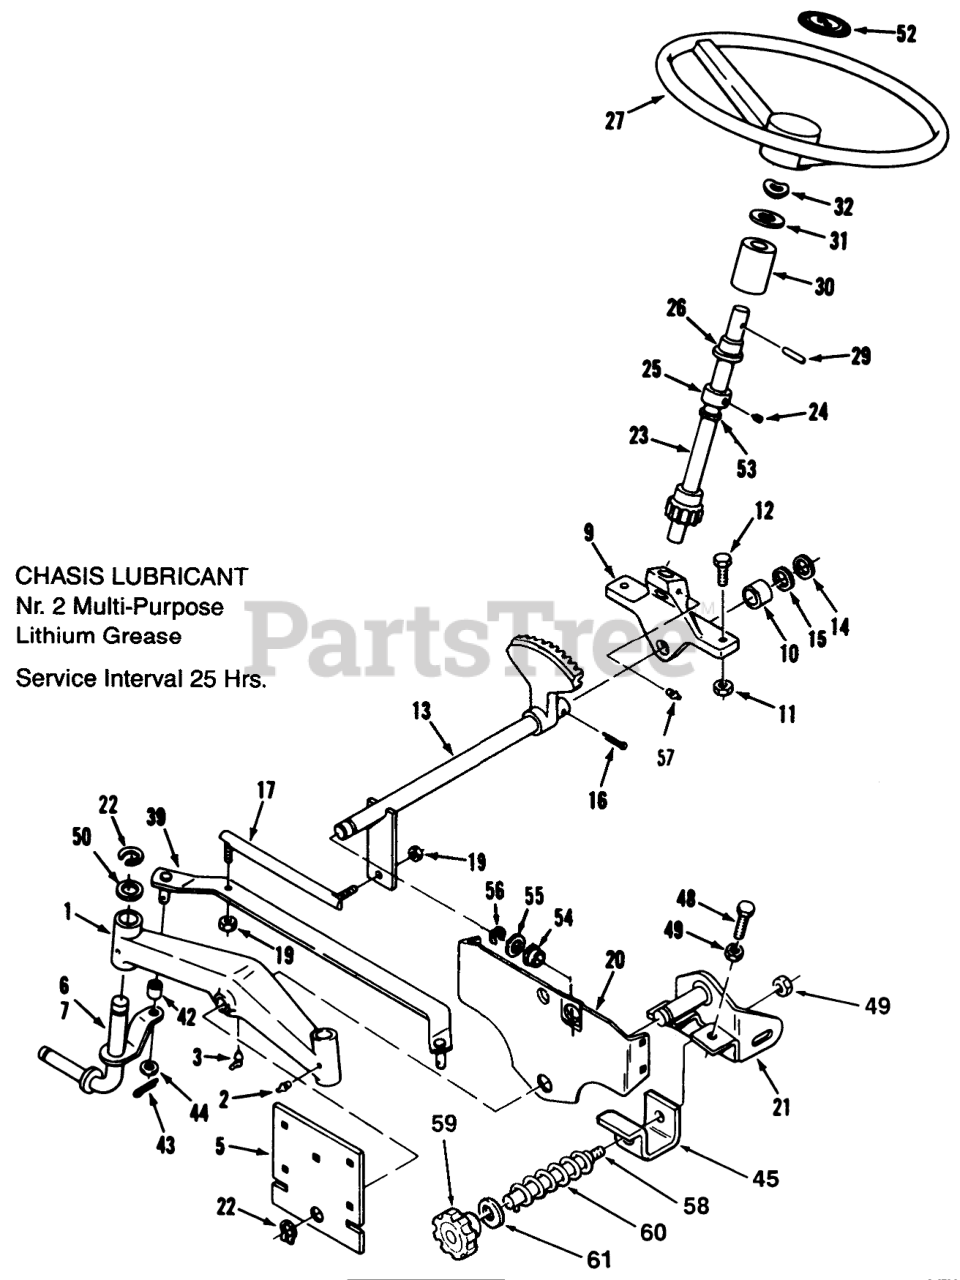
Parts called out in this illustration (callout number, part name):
1	AXLE-FRONT R
2	FITTING-GREASE
3	FITTING-GREASE
5	PLATE-FRONT AXLE R
6	Front Spindle Assy RH
7	Front Spindle Assy LH
9	Support
10	BEARING-BRONZE
11	NUT-LOCK, NI
12	SCREW-HH, LOCK
13	ASSY-STRG SHAFT L B
14	WASHER-SHIM
15	WASHER
16	PIN-COTTER
17	25LL JOINT ASSY R R
19	NUT-6
20	SUPPORT AXLE R
21	ASSY-FRONT HANGER R
22	RING-RETAINING
23	ASSY-STRG SHFT-UP R
24	PIN-ROLL 1/4 X 1 1/4
25	COLLAR
26	BEARING-FLANGED
27	Steering Wheel
29	PIN-ROLL
30	COLLAR
31	WASHER-FLAT
32	WASHER-BOWED
39	ASSY-TIE ROD R
42	SPACER
43	PIN-COTTER
44	WASHER
45	Yoke-Belt Adjusting
48	SCREW-HH
49	NUT-JAM
50	WASHER
53	RING-RETAINING
54	BUSHING
55	WASHER SPECIAL
56	RET RING
57	FITTING-GREASE, 90 DEG
58	Rod-Belt Adjusting
59	KNOB-LIFT CONTROL
60	Spring
61	WASHER-FLAT
